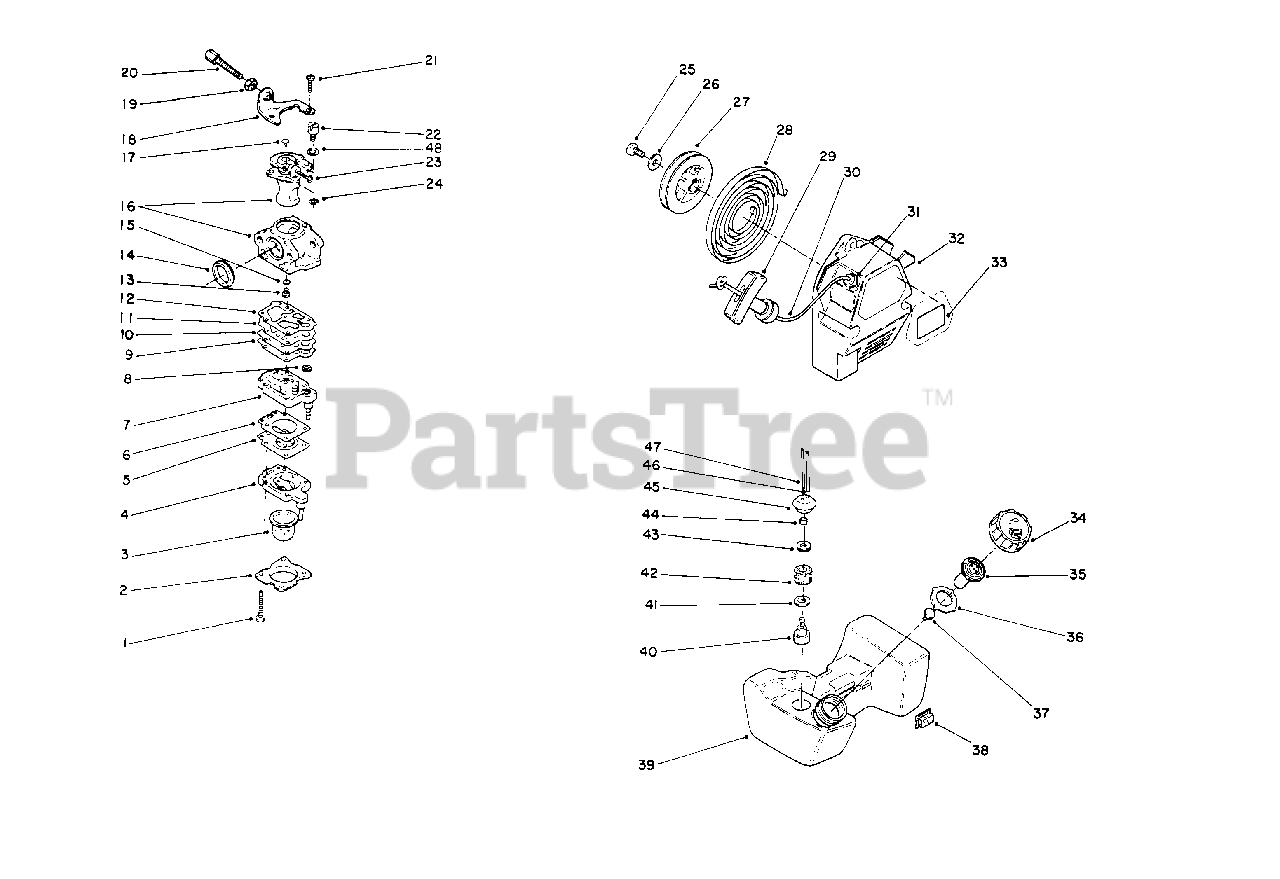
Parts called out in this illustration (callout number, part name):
2	Cover-Primer
3	Bulb-Primer
4	Body-Primer
5	Diaphragm
6	Gasket-Diaphragm
7	Body-Pump (Incl. Ref. #8)
9	Gasket-Pump
11	Diaphragm
12	Gasket-Diaphragm
13	Jet-Main #43
14	Gasket-Rubber
15	"O" Ring-Main Jet
16	Body-Carburetor (Ref.)
18	Bracket-Throttle
19	Nut-Lock
20	Screw-Adjustment
22	Swivel-Cable
23	Valve-Throttle
29	Handle-Recoil
30	Rope-Recoil
31	Guide-Rope
32	Case-Recoil
33	Decal-Toro
34	Cap-Fuel
35	Valve-Breather
37	Cap-Valve
39	Tank Assembly-Fuel (Incl. Ref. #34-37 & 40-47)
40	Weight-Filter
41	Washer-Seal
42	Filter-Fuel
43	Washer-Seal
45	Grommet-Fuel Tank
46	Hose-Fuel
47	Tube-Fuel Return
